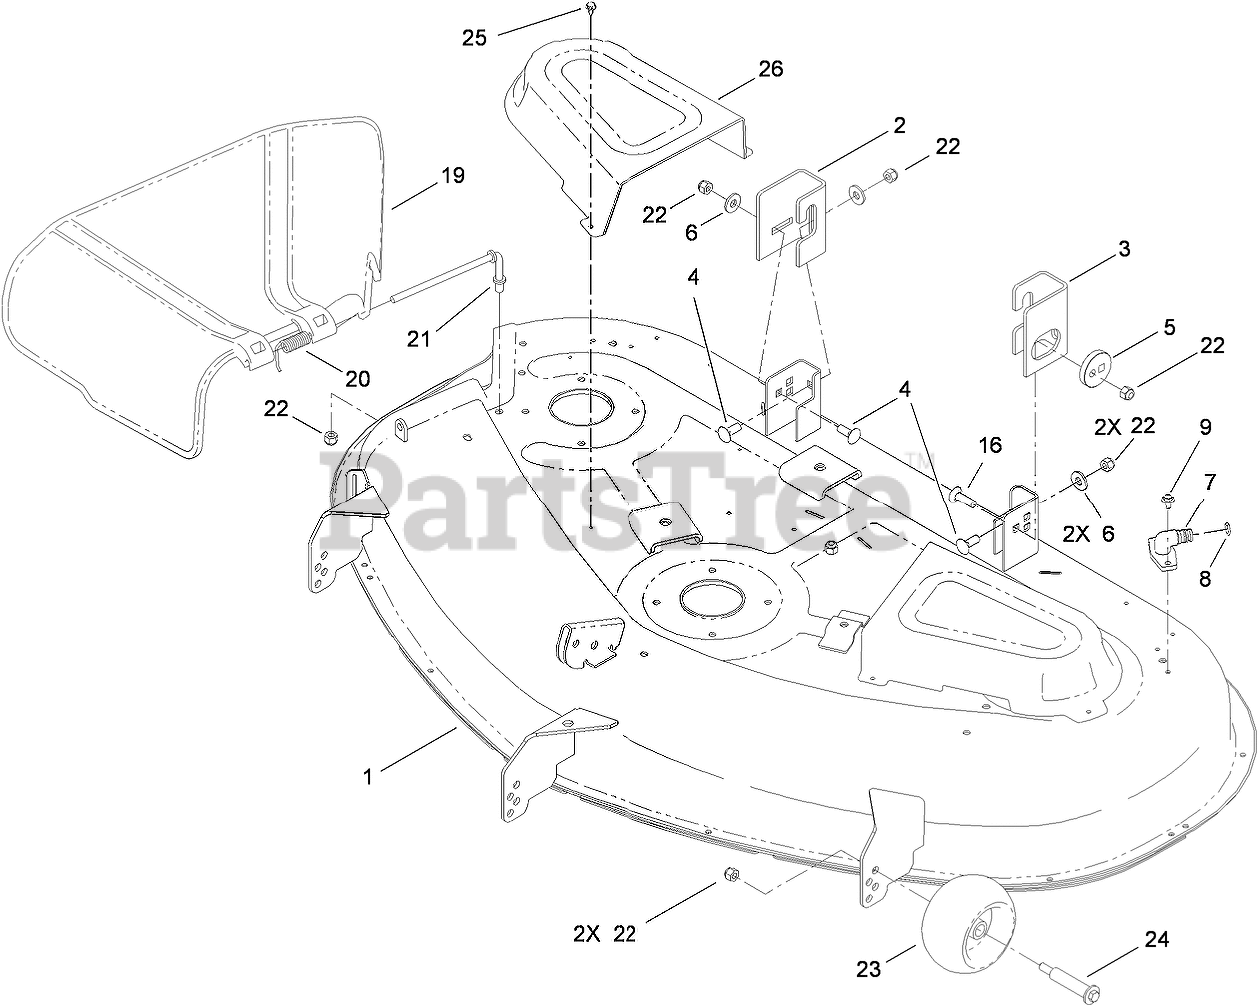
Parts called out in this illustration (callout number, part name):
1	50 INCH DECK ASM
2	BRACKET-HANGER, RIGHT REAR
3	BRACKET-HANGER, LEFT REAR
4	BOLT-CARR
5	ECCENTRIC
6	WASHER-HARDENED
7	FITTING-WASHOUT
8	O-RING
9	SCREW-HHFTF
16	SCREW-CARR
19	DEFLECTOR
20	SPRING-TORSION
21	ROD-PIVOT
22	NUT-LOCK, NI
23	ROLLER-SCALP, ANTI
24	BOLT-SHOULDER
25	SCREW-HWHTF
26	COVER-BELT
